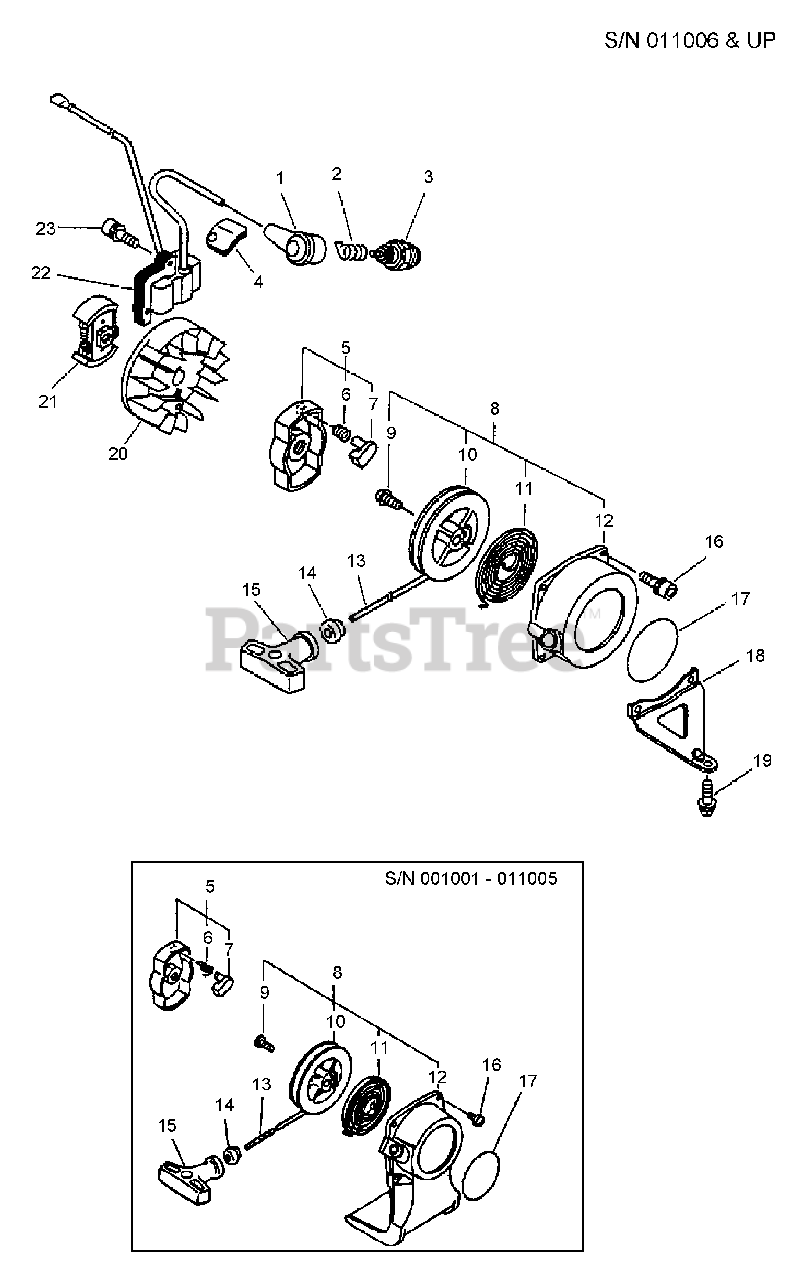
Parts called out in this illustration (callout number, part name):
1	CAP, SPARK PLUG
2	TERMINAL, SPARK PLUG
3	SPARK PLUG - BPM7A
5	PAWL ASSY, STARTER
6	SPRING, RETURN
7	PAWL, STARTER - BLACK
8	STARTER ASSY
8	STARTER ASSY, RECOIL
9	SCREW
10	REEL, ROPE
11	SPRING, RECOIL
12	CASE, RECOIL STARTER
14	GUIDE, ROPE
15	GRIP, STARTER
16	BOLT 4×16
17	LABEL, ECHO
18	SUPPORT, HANDLE
19	SCREW 5×16
20	FLYWHEEL
21	CLUTCH ASSY
22	COIL, IGNITION
23	SCREW 4×22
